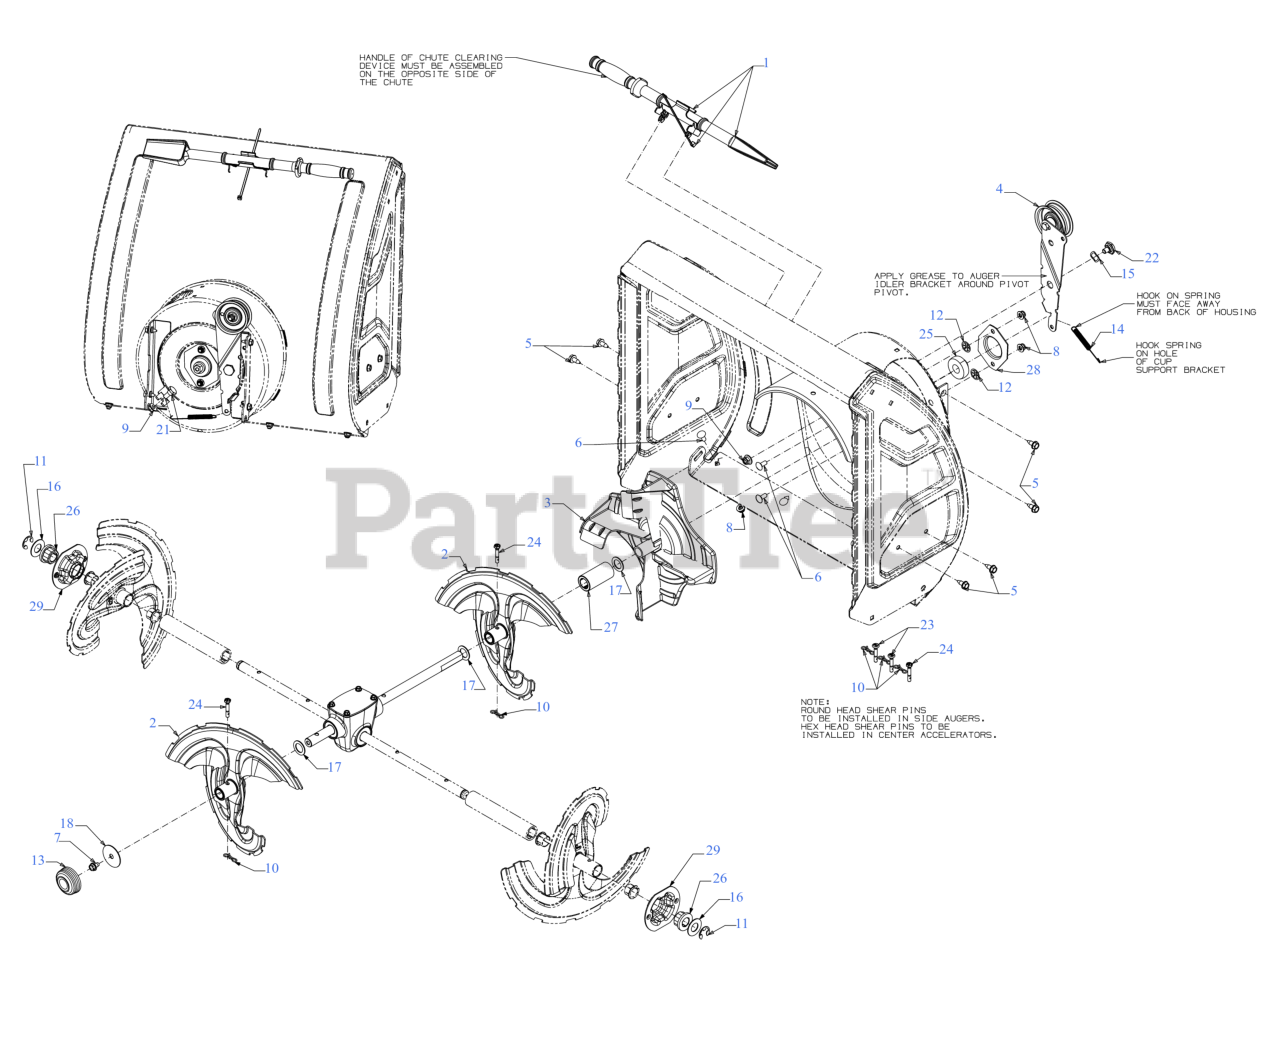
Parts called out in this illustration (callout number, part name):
5	SCREW 5/16-18 x .750
6	CARRIAGE BOLT 5/16-18 x .75
7	SCREW 5/16-18 x .500
8	FLANGE LOCK NUT 5/16-18
10	BOW TIE COTTER PIN 1/4-5/16
11	E-RING
12	PUSH NUT
14	EXTENSION SPRING .38 OD x 4.59
15	WAVE WASHER .660 ID X.88 OD x .010
16	FLAT WASHER .760ID X1.49OD x .06
17	FLAT WASHER .793 ID X1.240X.06
18	HUB CAP WASHER .406 x 1.92 x .060
21	SHOULDER SCREW .498 DIA x .340
22	SHOULDER SCREW .625 DIA x .163
23	SHEAR PIN (.25 x 1.50)
24	SHEAR PIN (.25 x 1.5)
25	BEARING W/OUT COLLAR
26	FLANGE BEARING
28	BEARING HOUSING 1.85 ID
